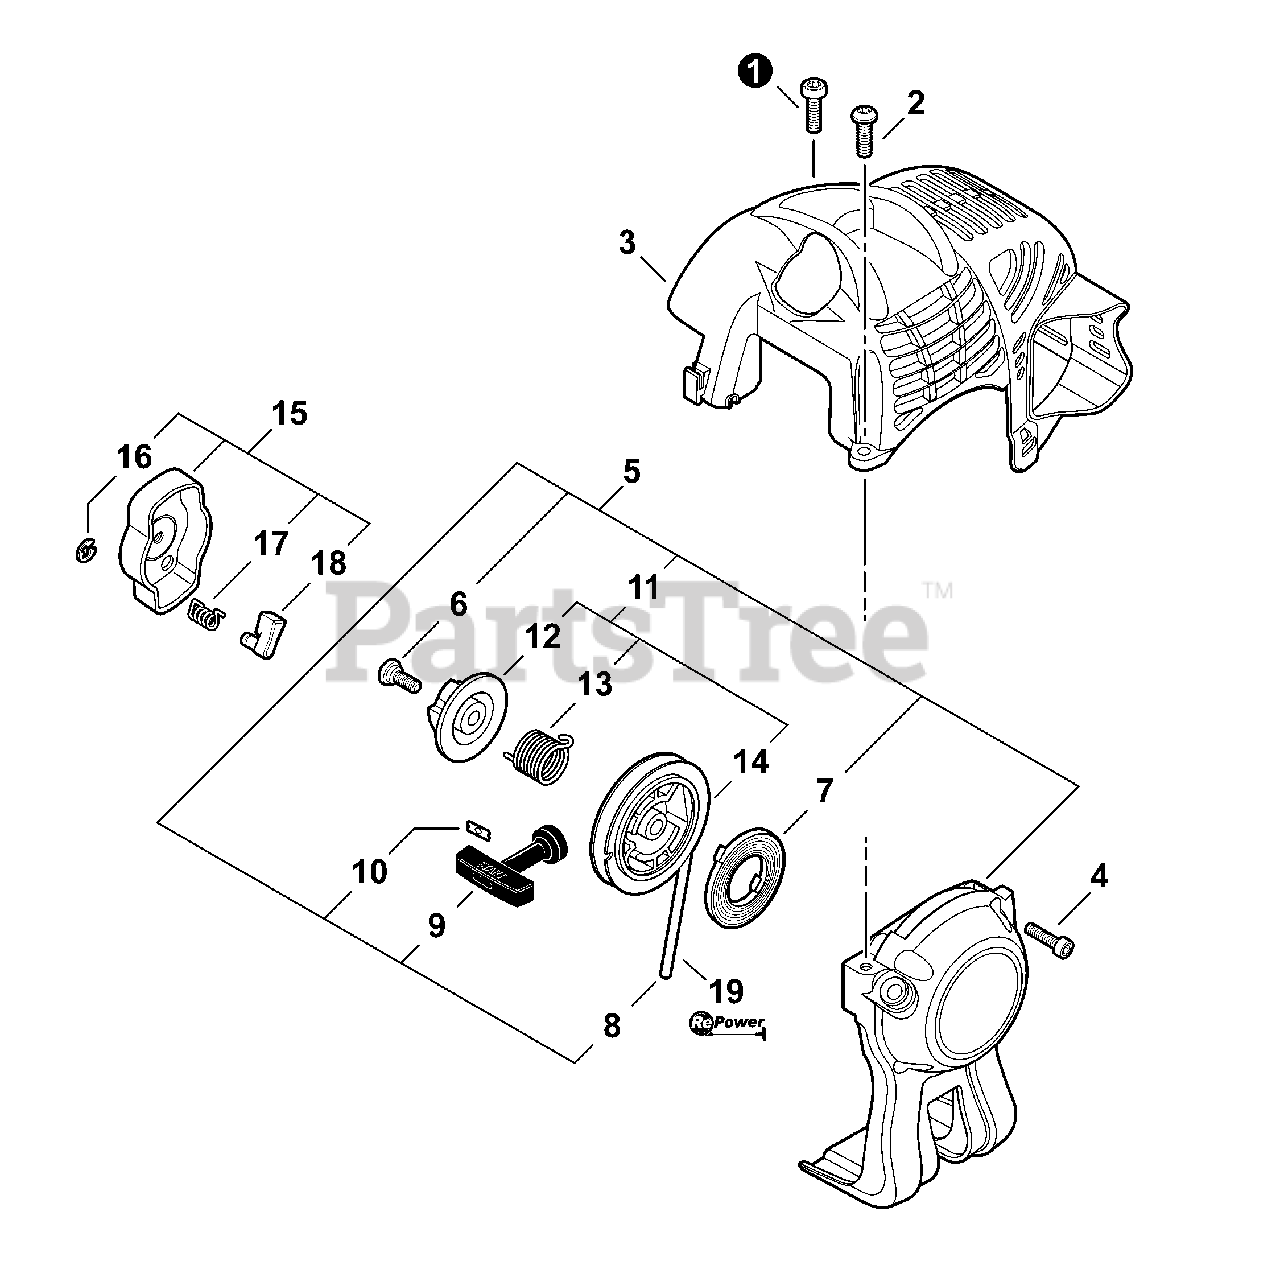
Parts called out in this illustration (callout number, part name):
1	SCREW - 5×16
2	SCREW - 5×16
3	COVER, ENGINE
4	SCREW - 4×16
5	STARTER ASSY
6	SCREW
7	SPRING, REWIND
8	ROPE, STARTER - 3×700
9	GRIP, STARTER
10	RETAINER, ROPE
11	ROPE REEL KIT
12	PLATE, CAM
13	SPRING, DAMPER
14	REEL, ROPE
15	STARTER PAWL ASSY
16	RING, RETAINING - 4
17	SPRING, RETURN
19	ROPE, STARTER - REPOWER BULK
